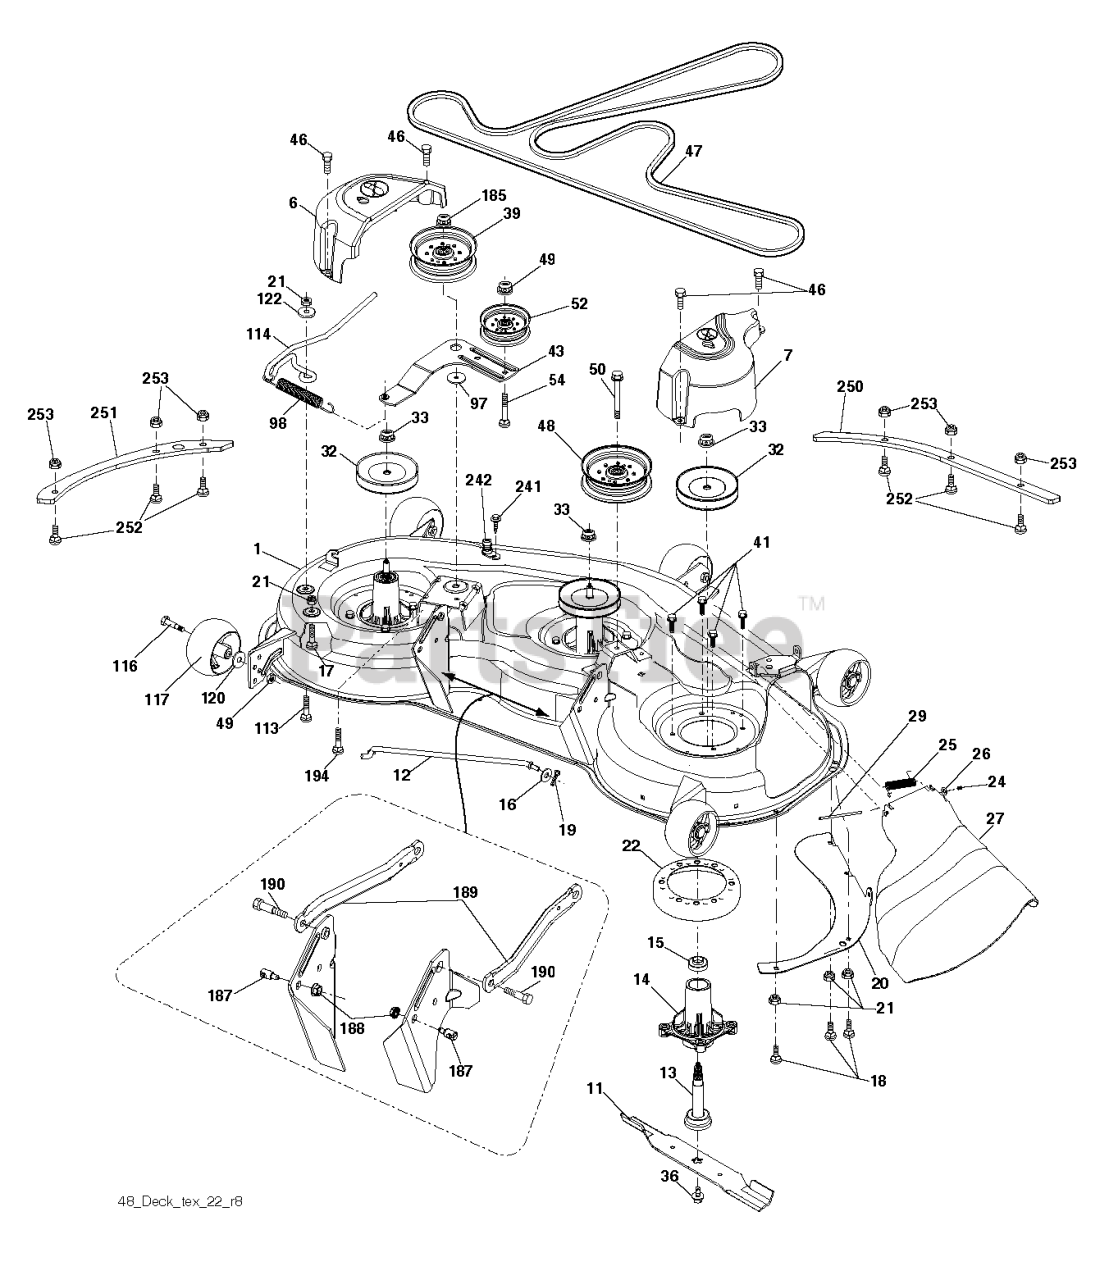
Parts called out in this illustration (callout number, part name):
1	DECK.SVC.48"
6	COVER.MANDREL.LH.48"(2 2)
7	COVER.RH.MANDREL
11	48" HI-LIFT BLADE
12	ROD.ANTI.SWAY.48/54"K4
13	SHAFT ASSY, MANDREL SHAFT
14	RP.HOUSING.MANDREL.4PT.
15	BEARING.MANDREL.TOP.EXTENDED
16	WASHER
17	BOLT.CARR.5/16-18X5/8.SHORT
18	BOLT
19	PIN.COTTER.5/16.BOW TI
20	BAFFLE, VORTEX MWR
21	LOCKNUT
22	STRIPPER.MANDREL.ROUND.BLACK
24	CAP-SLEEVE LT
25	SPRING, TORSION
26	NUT PUSH M
27	DEFLECTOR SUBS TO 532 180655
29	ROD.HINGE
32	PULLEY MANDREL
33	NUT.FLANGE.LOCK.TOP
36	SCREW.SEMS.7/16-20X1.HEX.HEAD
39	RB PULLEY.IDLER.4.50/HUB SPEC
41	BOLT.HEX.WASHR.HED.313-18X1.19
46	SCREW.1/4-20X5/8
47	BELT.DRIVE.DECK
48	PULLEY.IDLER.2006
49	NUT LOCK FLG 3/8-16 UNC
50	SCREW TT 3/8-16X2.31 UNC
50	SCREW TT 3/8-16X2-1/4 UNC
52	PULLEY.IDLER.48"PRIMARY
54	BOLT.3/8-16X1.50
98	SPRING, DECK DRIVE
113	RHSSNB 5/16C X 1.0
114	ROD.TENSION.RELIEF.TEX (2 2)
116	BOLT.SHOULDER.3/8-16X3-5/8.
117	WHEEL.GAUGE.RALLY
120	WASHER
122	BUSHING.RELIEF.TENSION
185	NUT.LOCK.FLANGE.7/16
187	STUD.FASTNER.W/ANTI-ROTATE
188	NUT LOCK HEX FLANGE 5/16-18
189	ARM.SUSPENSION.MOWER
190	BOLT.SHOULDER
194	BOLT.HEX.WASHER.HEAD.7/16-24X
241	SCREW.TT.#10-32X.5.3/8.FLANGE
242	PORT.WASHOUT
250	PLATE.REIN.FRNT.BOLTON.48X431
251	PLATE.REIN.SIDE.BOLT.ON.48X431
252	RHSNB, 1/4-20 X 1, GR5
253	NUT T
